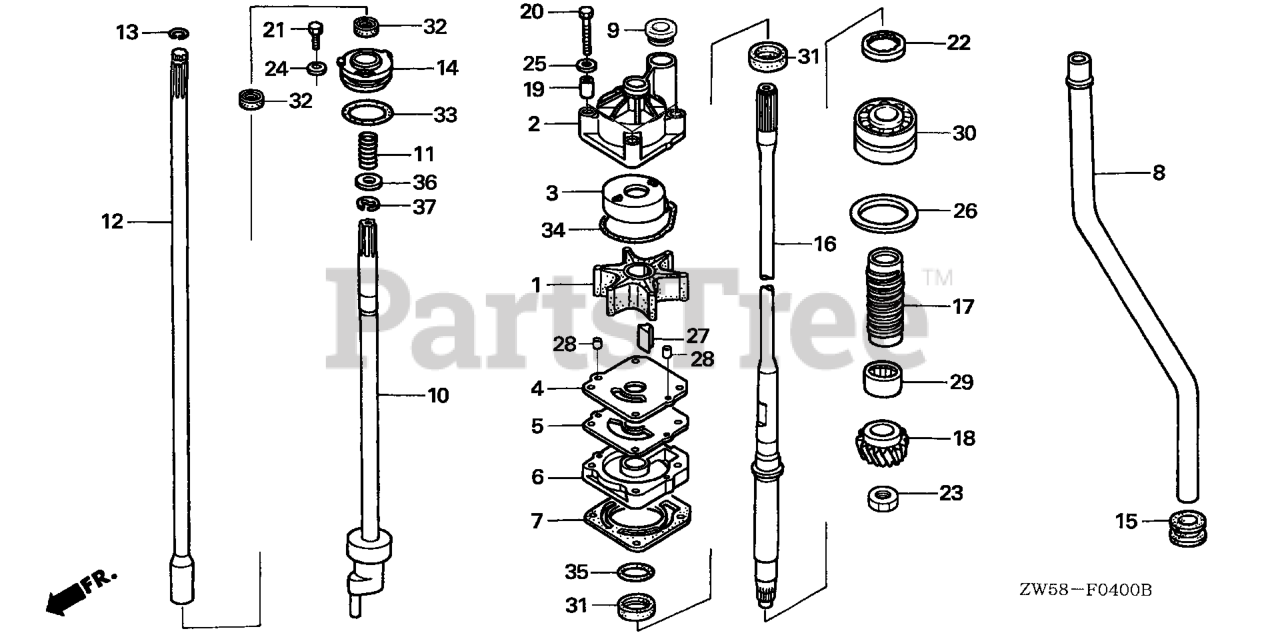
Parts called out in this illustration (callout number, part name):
1	IMPELLER, PUMP
2	HOUSING, IMPELLER
3	LINER, PUMP
4	COVER, IMPELLER
5	GASKET B, IMPELLER
6	HOUSING, WATER PUMP
7	GASKET, WATER PUMP
8	TUBE, WATER (L)
9	RING, WATER TUBE SEAL
10	ROD, SHIFT (COUNTER ROTATION)
11	SPRING, SHIFT ROD
12	ROD A, SHIFT (L)
13	RING, STOPPER
14	HOLDER, SHIFT ROD
15	GROMMET, EXTENSION CASE
16	SHAFT, VERTICAL
17	SLINGER, OIL
18	GEAR, PINION
19	COLLAR, DISTANCE
20	BOLT, HEX. (8X55)
21	BOLT, HEX. (6X12) Use up to Frame SN 1005248.
22	NUT, LOCK (64MM)
23	NUT, HEX. (18MM)
24	WASHER, PLAIN (6MM)
25	WASHER (8MM)
26	SHIM A, GEAR (0.10)
26	SHIM B, GEAR (0.15)
26	SHIM C, GEAR (0.30)
26	SHIM D, GEAR (0.50)
27	KEY, WOODRUFF
28	PIN, DOWEL (6X10)
29	BEARING, NEEDLE (1-1/2X1-1/4)
30	BEARING, TAPER ROLLER (30X62X40)
31	SEAL, WATER (23X36X6) Use up to Frame SN 1300340.
32	SEAL, WATER (12X21X6)
33	O-RING (49.4X3.1)
34	O-RING, WATER PUMP
35	O-RING (58.5X3.5)
36	WASHER, PLAIN (12MM)
37	E-RING (10MM)
